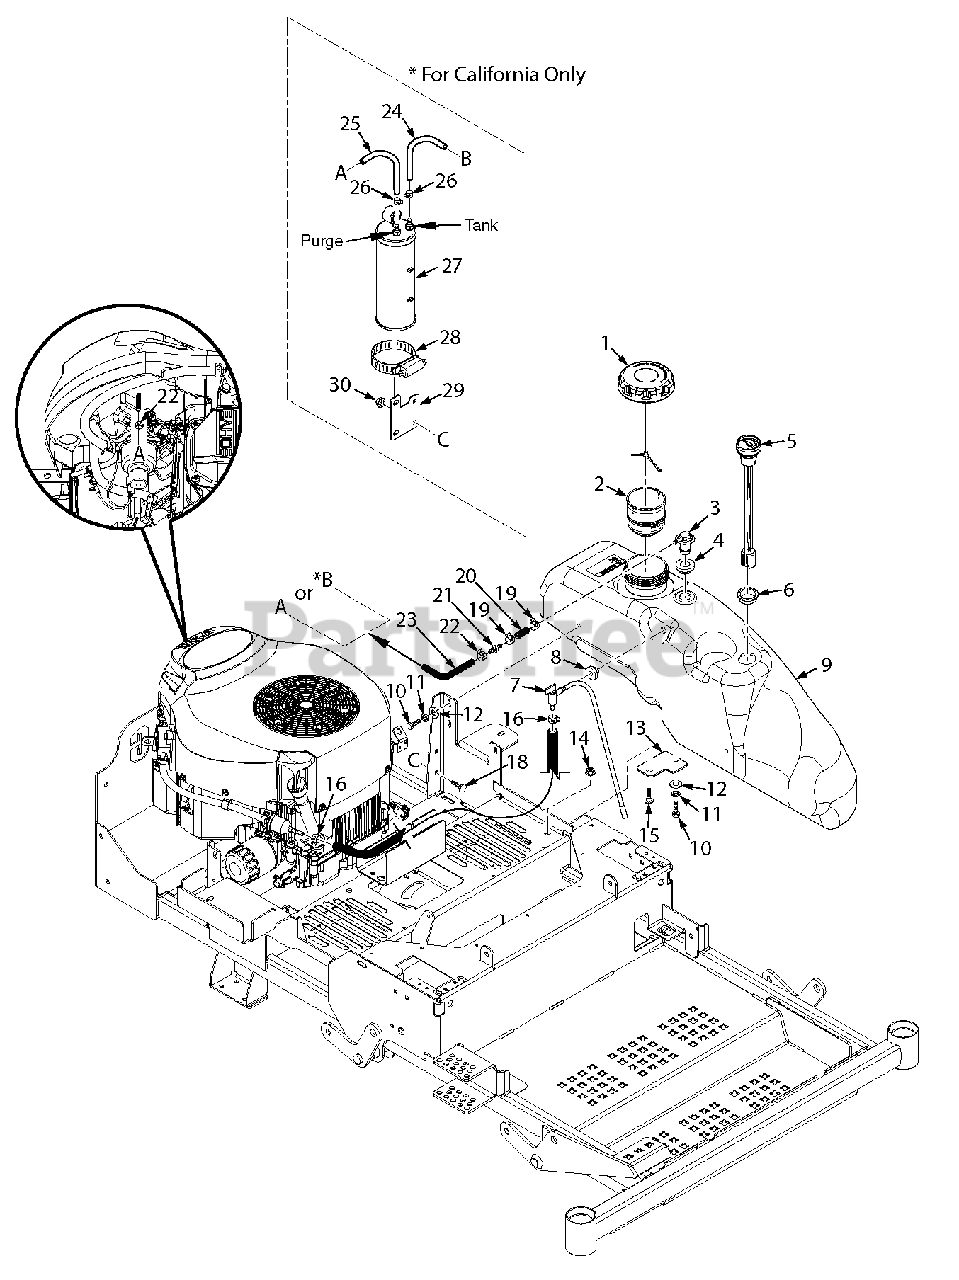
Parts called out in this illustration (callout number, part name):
1	Fuel Cap
1	Fuel Cap, C.A.R.B.
2	Fuel Neck Insert
3	Remote Vent, No Valve
4	Grommet, Kelch
5	Fuel Gauge (requires #6)
6	Grommet, Fuel Gauge
7	Valve, Fuel Shut Off
8	Bushing, .56 Dia. Viton
9	Fuel Tank Assembly
10	Bolt, Hex Head 5/16-18 x 3/4"
11	Lockwasher, 5/16"
12	Flatwasher, 5/16-.375 x .875 x .083
13	Mounting Bracket, Fuel Tanks Front
14	Nut, 5/16-18 Serrated Flange
15	Bolt, Carriage 5/16-18 x 1"
16	Clamp, Fuel Hose 1/4"
17	Hose, Non-perm Fuel - 1/4" Dia. (order by inch)
18	Bolt, Carriage 1/4-20 x 3/4"
19	Clamp, Fuel Hose 7/32" ID
20	Hose, 1/4" Vapor Return (order by inch)
21	Mender, 1/4 x 3/16 w/.02 Hole
22	Clamp, Vapor Hose -3/16"
23	Hose, Vapor (order by inch)
24	Hose, Vapor (order by inch)
25	Hose, Vapor (order by inch)
26	Clamp, Vapor Hose - 3/16"
27	Carbon Cannister, 400cc
28	Clamp, 3-1/2" Max. Dia.
29	Bracket, Cannister Mount
30	Nut, 1/4-20 Serrated Flange
